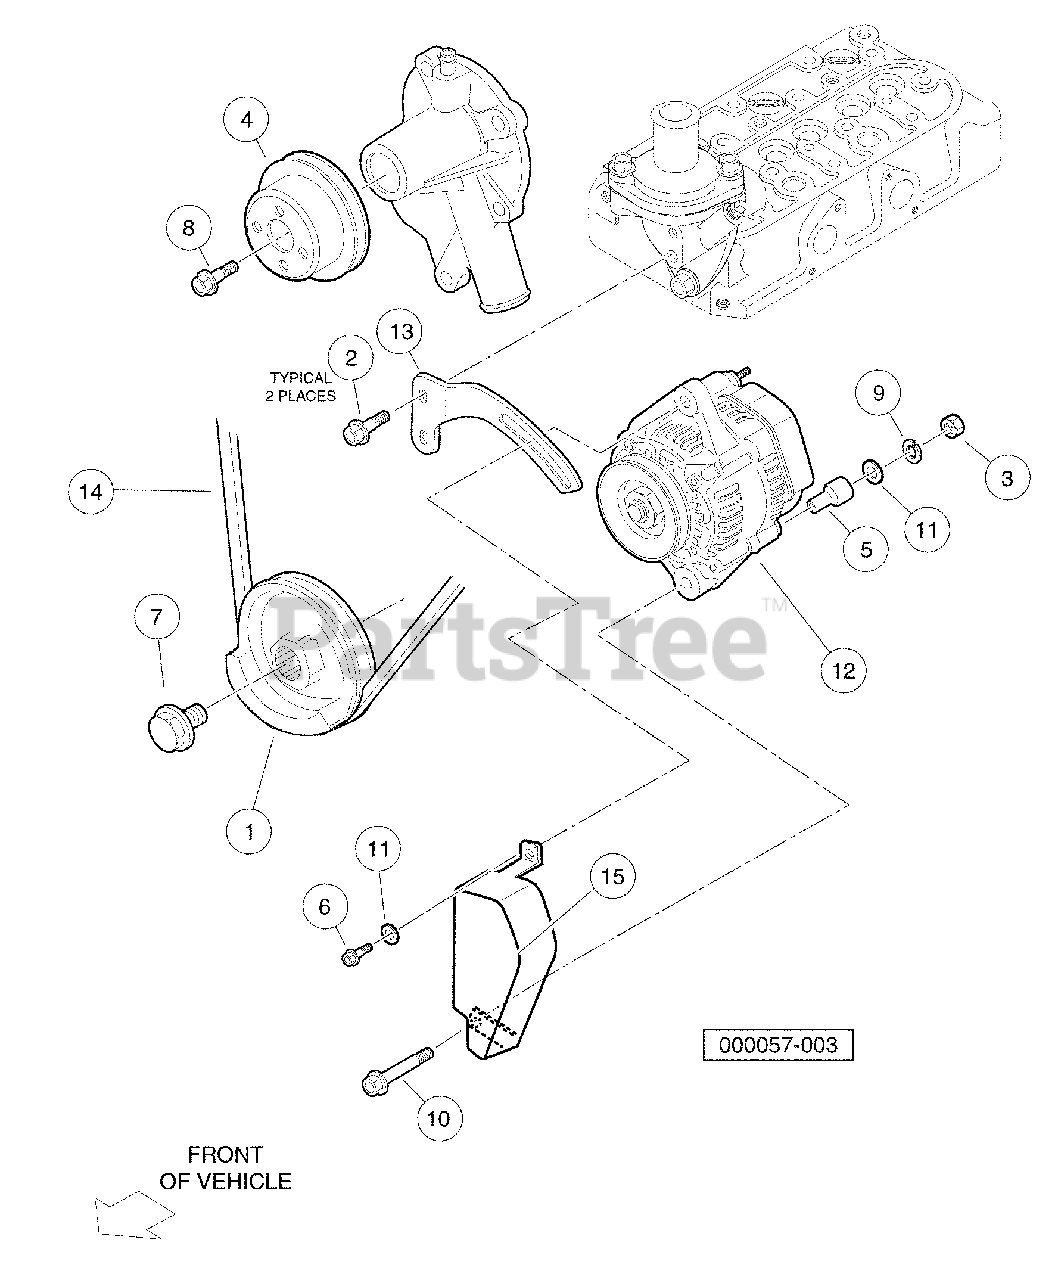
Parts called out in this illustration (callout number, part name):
1	Pulley, Fan Drive
2	Bolt, M6 X 1 X 20
3	Nut, M8, Plate
4	Pulley, Water Pump
5	Collar, Alternator Assy, D722
6	Bolt, Alt, D722, Adjuster
7	Bolt, Alt, D722, Drive Pulley
8	Bolt, D722, Drive Pulley
9	Washer, Spring, D722, Starter
10	Bolt, Alternator, Lower
11	Washer, Alternator, Upper
12	Alternator, 60 Amp
13	Brkt, Alt, D722, 60 Amp
14	Belt, Acc Drive, D722, 60 Amp
15	Guard, Acc Belt
